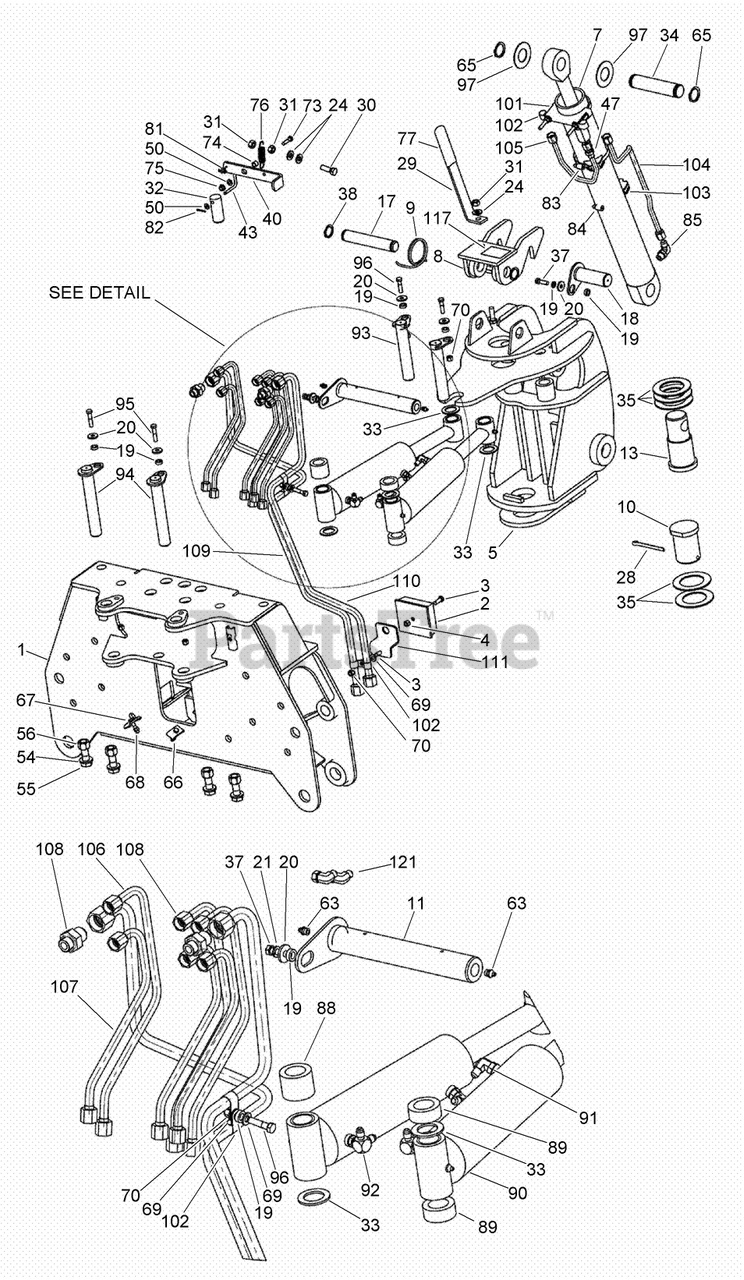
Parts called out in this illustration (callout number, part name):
1	FRAME-Backhoe Attachment
2	BUMPER
3	SCREW-HH
4	NUT
5	WELDMENT-Frame, Pivot
7	HYD CYLINDER ASM
8	LATCH-Boom Lock
9	SPRING-Torsion
10	PIN-PIVOT, LOWER
11	PIN-BOOM PIVOT
13	PIN-PIVOT, UPPER
17	PIN-PIVOT
18	PIN-Boom Cylinder
21	WASHER-Spring Lock, Reg 3/8 ZND
24	WASHER-FLAT
28	PIN-COTTER
29	HANDLE-Control
30	SCREW-HH
31	NUT-LOCK, HEX
32	PIN-Control Lever
35	WASHER-THRUST PIVOT
37	BOLT
38	RING-RETAINING
40	LEVER-Control
47	CONNECTOR-Str Thd 1/2, 37FL-ORB 1/2
50	WASHER-FLAT
54	WASHER-Flat
56	NUT-HEX LOCK
63	FITTING-Lube 1/8-27 Dryseal PTF
66	CLAMP-TUBE
67	BOLT-Hex, 5/16 NC x 1-1/2 inch
68	NUT-Prev Trq 5/16 GRA CAD NONDIR
69	WASHER-FLAT
70	NUT-HEX
73	BOLT-Hex, 5/16 NC x 1-1/4 inch
74	BUSHING
75	NUT-Hex Serrated Flange, 5/16 inch NC
77	GRIP-HANDLE
81	WASHER-FLAT
82	PIN-Cotter, 1/8 x 3/4 inch
83	CLAMP-Hose Type F #72
84	CLAMP-Hose Type F #60
85	ELBOW-90 DEG
88	BOSS-PIN (40MM)
89	BOSS-PIN (20.5MM)
90	HYD CYLINDER ASM
91	ELBOW-90 DEG (ADJUSTABLE 37 DEG)
92	FITTING
93	PIN-PIVOT W/FLAG
94	PIN-PIVOT W/ FLAG
95	BOLT-Hex Hd .375 x 1.75 GR5 ZND
96	BOLT-hex, 3/8 NC x 1-1/2 inch
102	CLAMP-Insul 19.0 mm 3/8 in Bolt ZND
103	SADDLE-SUPPORT, TUBE
104	CYLINDER-Hydraulic Tube (base end)
105	CYLINDER-Hydraulic Tube (rod end)
106	VALVE-Top Port, Hydraulic Tube
107	VALVE-Bottom Port, Hydraulic Tube
108	CONNECTOR-Str Thd 3/4, 37FL-ORB 5/8
109	TUBE-Hydraulic, Backhoe Supply
110	TUBE-Hydraulic, Backhoe Return
111	PLATE-Tube Bracket
117	DECAL-BH Transport Lock
121	FITTING-ELBOW, 90
